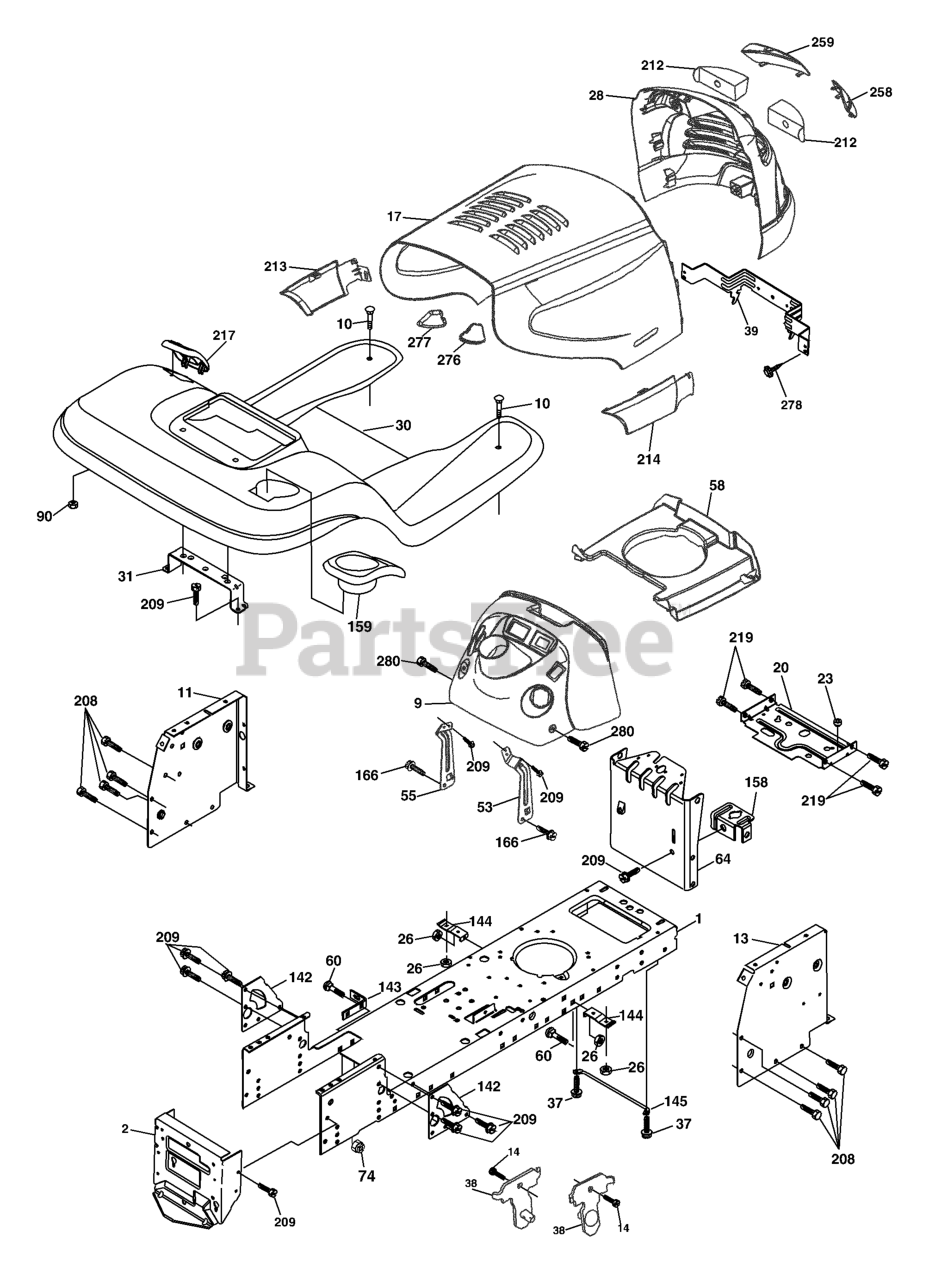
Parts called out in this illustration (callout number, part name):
1	CHASSIS STAMPING
2	DRAWBAR, 12GA
9	DASH
10	BOLT D
11	PANEL.DASH.LH.LTX
13	PANEL ASM, DASH RH
14	SCREW LT
17	HOOD
20	PLATE MTG.BATTERY/FUEL TANK
23	BUSHING.SNAP.NYL.BLK.
26	NUT
28	GRILL/LENS ASSY ( YT MODEL)
30	FENDER
31	BRACKET.SUPPORT.FENDER
37	Screw Thdrol 5/16-18 x 1/2
38	BRACKET.ASM.PIVOT.MOWER.REAR
39	BRACKET PIVOT LASER
53	BRACKET DASH RH
55	BRACKET DASH LH
58	AIR DUCT
60	Bolt RDHD SQNK 3/8-16 x 3/4
64	DASH LOWER
90	NUT.PUSH.3/16
142	PLATE REINFORCEMENT
143	BRACKET, SWAYBAR CHASSIS
144	BRKT, FOOT REST
145	ROD PIVOT CHASSIS/HOOD
158	BRACKET PARKING BRAKE
159	GREY CUP HOLDER
166	SCREW
208	SCREW 3/8-16X1/2
209	SCREW, 3/8-16X3/4
212	INSERT LENS
213	SKIRT SIDE LH
214	SKIRT SIDE RH
217	CONSOLE FUEL WINDOW
219	SCREW
258	LENS ELITE CLEAR RH
259	LENS ELITE CLEAR LH
276	BUMPER HOOD RH
277	BUMPER HOOD LH
278	SCREW
280	SCREW THDROL 3/8-16 X 1-1/2
